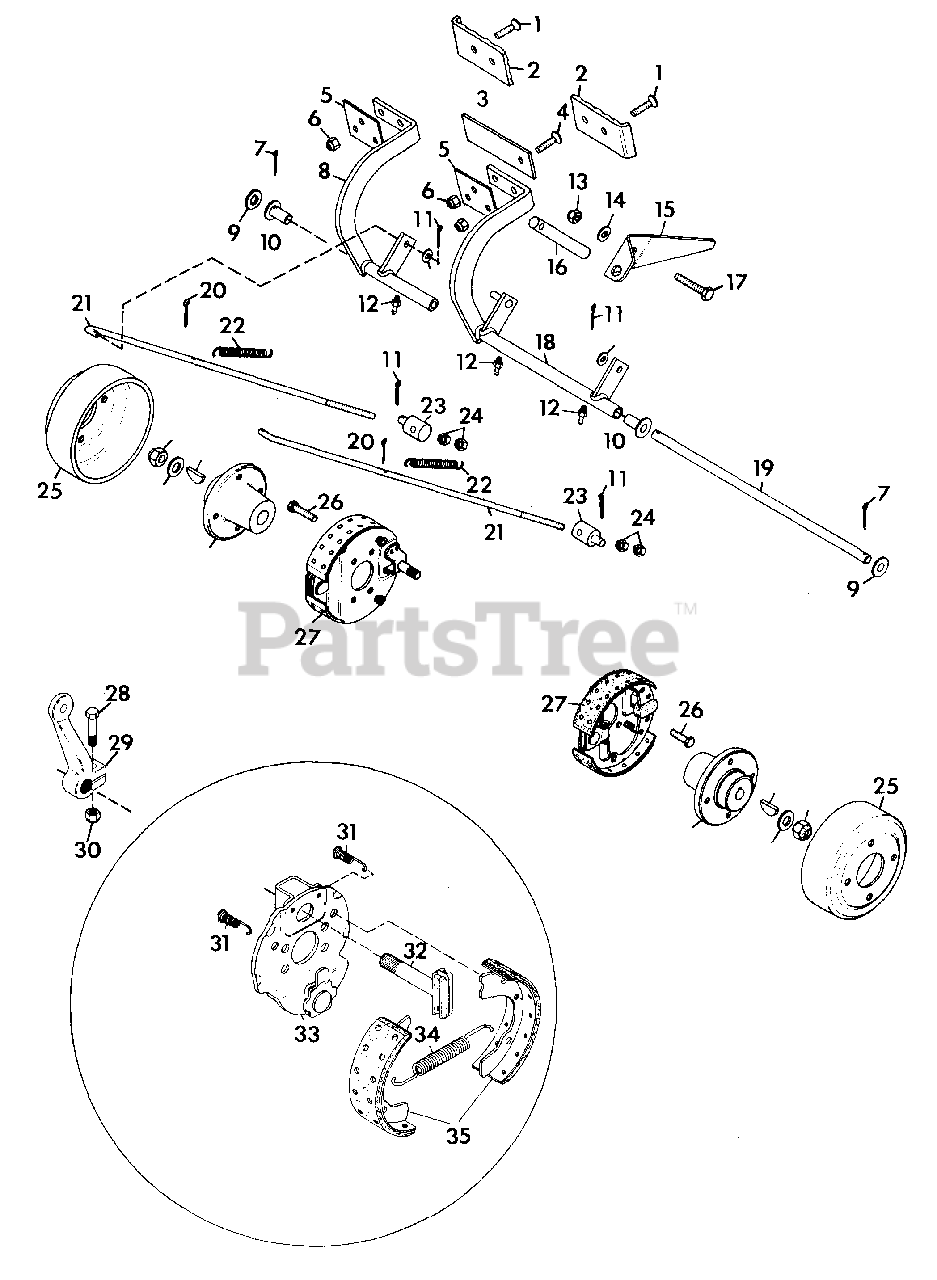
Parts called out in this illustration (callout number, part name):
1	SCREW, MACHINE 1/4-20X1.25
2	PEDAL, BRAKE
3	ARM, BRAKE LOCK
4	SCREW, MACHINE 1/4-20X1.0
5	PLATE, BRAKE LOCK BACKING
6	NUT, LOCK 1/4-20
7	PIN, COTTER .125X1.25
8	WELDMENT, BRAKE PEDAL
9	WASHER, FLAT .656X1.250X.100
10	BEARING
11	PIN, COTTER .09X.75
12	FITTING, LUBE 1/4-28
13	NUT, LOCK 3/8-16
14	WASHER, NYLON .375X.75X.060
15	LEVER, BRAKE LOCK
16	ROD
17	BOLT, HEX 3/8-16X2.25
18	WELDMENT, BRAKE PEDAL
19	SHAFT, BRAKE
20	PIN, COTTER .125X.75
21	ROD, BRAKE
22	SPRING, EXTENSION 5.5X.5X20 RATE
23	PIVOT, BRAKE
24	NUT, JAM 3/8-24 HEX HD
25	DRUM, 7X1.75
26	BOLT, HEX 3/8-16X.75
27	BRAKE, 7X1.75 MECHANICAL
28	BOLT, HEX 5/16-18X1.25
29	LEVER, BRAKE L.H.
29	LEVER, BRAKE R.H.
30	NUT, LOCK 5/16-18
31	SPRING, SHOE RETAINING
32	CAM, BRAKE
33	PLATE, BACK
34	SPRING, SHOE RETURN
35	SHOE, BRAKE
